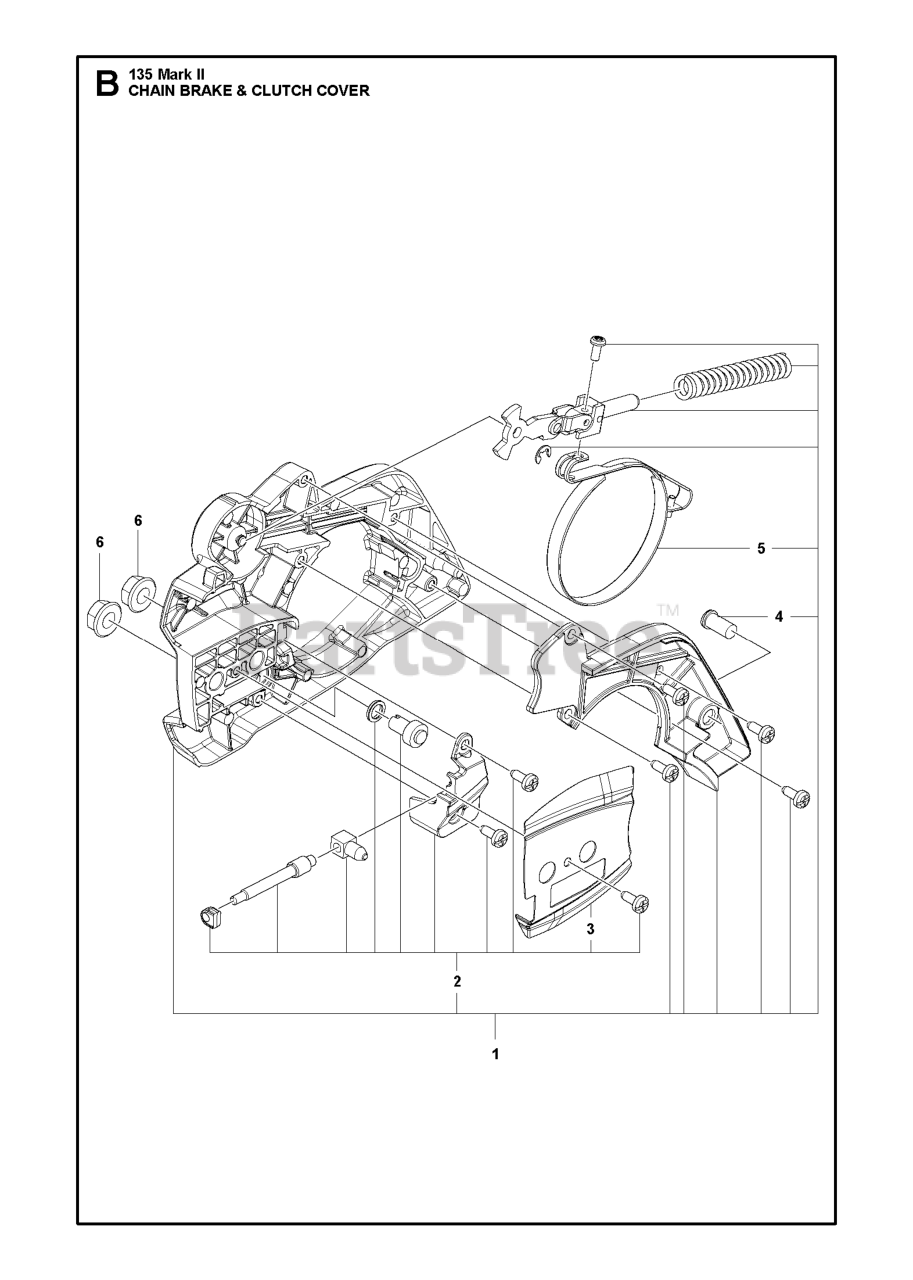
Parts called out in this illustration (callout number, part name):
1	KIT SVC CLUTCH COVER 135 MK II
2	SERVICE KIT BAR ADJUSTER 135 M
3	GUIDE PLATE CHAIN, OUTSIDE
4	GUIDE BUSHING
5	BRAKE BAND ASSY
